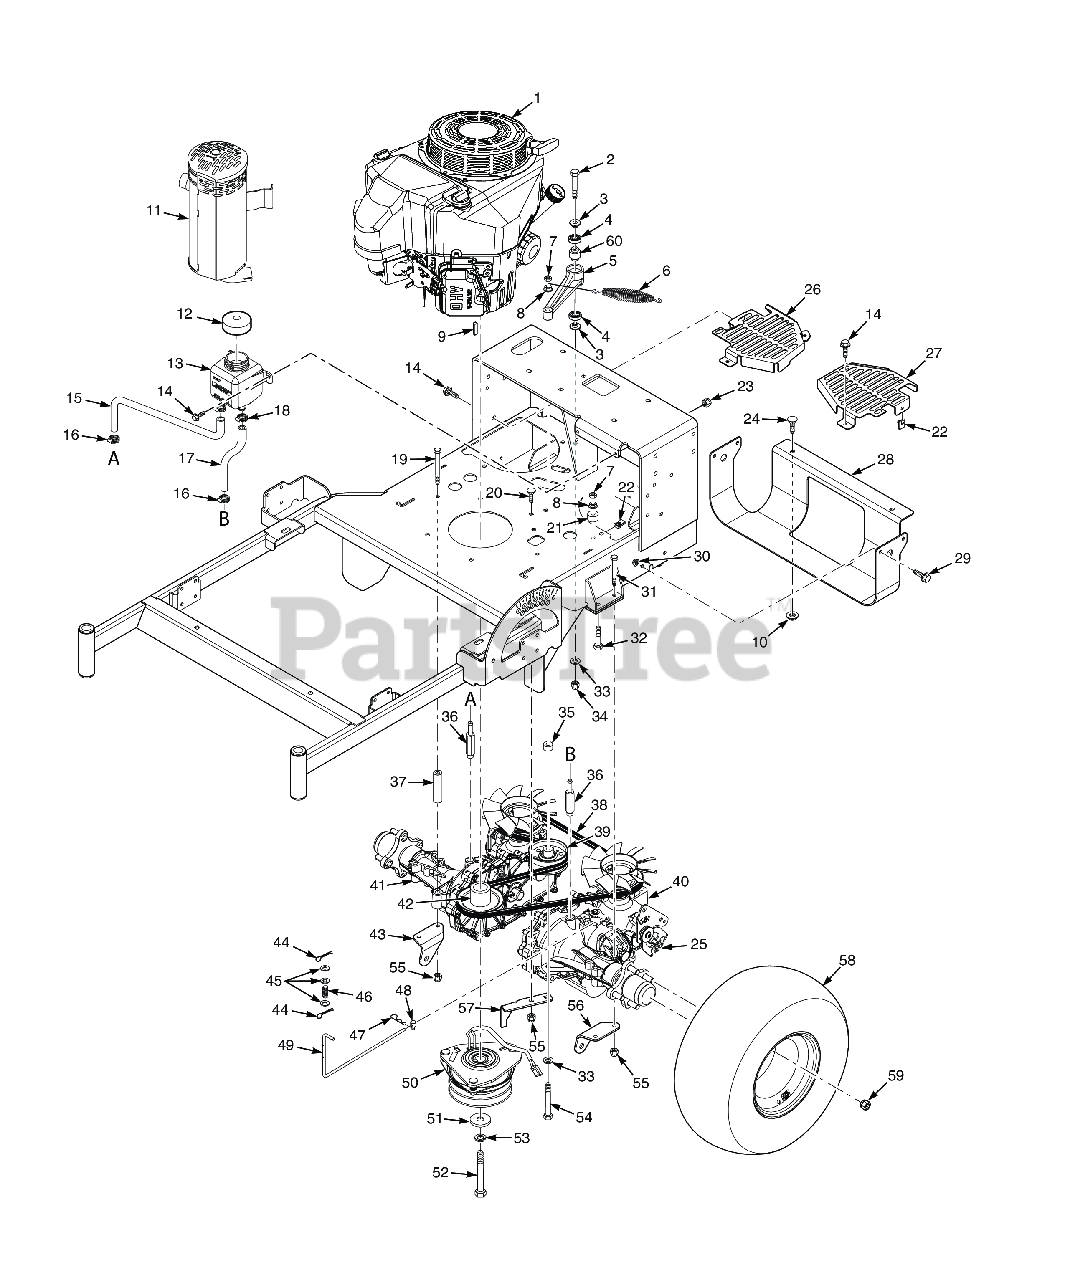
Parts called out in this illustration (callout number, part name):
1	Engine, Kawasaki 14FS (FS481V)
1	Engine, Kawasaki 15FS (FS541V)
1	Engine, Kawasaki FS600V (Recoil Start)
1	Engine, Kawasaki FS600V (Electric Start)
1	Engine, Kawasaki FS651V (Electric Start)
2	Bolt, Hex Head 3/8-16 x 3" - 52"
3	Spacer, Controls
4	BEARINGS, BALL, NEUTRAL RETURN
5	Trans. Idler Arm Assy. (Includes 24, 79)
6	Spring, Transmission Idler
7	Bolt, Hex Head 3/8-16 x 1" Ser. Flg.
8	NUT, 3/8-16 SERRATED FLANGE HEX HEAD
9	KEY, 1/4 X 1/4 X 2-1/2"
10	Nut, Push-On 5/16-18
11	Muffler, Kawasaki (FS481, FS541, FS600)
12	Cap, Hydraulic Tank
13	Reservoir Assembly
14	Bolt, Serrated Flange Hex Head 1/4 x 20 x 3/4"
15	Hose, RH Transmission
16	Clamp, .69" Max. / .25" Min. Dia.
17	Hose, LH Transmission
18	Clamp, Cable 3/4" I.D.
19	Bolt, Hex Head 5/16-18 x 6-1/2"
20	Bolt, Carriage 5/16-18x1" (large frame units only)
21	SPACER, J PULL ROD
22	Bolt, Hex Head 3/8-16 x 1"
23	HEX, NUT, ELASTIC STOP LOCK, 1/4-20
24	Bolt, 5/16-18 x .75 RHSN Carriage
25	Spring, RTN
26	Fan Cover, RH
27	Fan Cover, LH
28	Skid Plate
29	Capscrew, 5/16-18 x .75 Serrated Flange Hex Head
30	Nut, Serrated Flange 5/16-18 (Right Front Engine Mounting, Briggs and Kohler Only)
31	Bolt, Hex Head 5/16-18 x 3.00"
32	Bolt, Hex Head 3/8-16 x 2-1/2" 1.5 Thread Grd.8
33	Flatwasher, 3/8 (.391 x .938 x .105 HD) Grade 8
34	HEX NUT, ELASTIC STOP LOCK, 3/8-16
35	Spacer, Idler Pulley - SFZ61
36	Fitting, Transmission - SFZ61
37	Spacer, Axle
38	Belt, Transmission Drive
39	Pulley, 3-1/2" Dia.
40	Transaxle Assy., (ZH-GMCC-3LUB-1MXX)
41	Transaxle Assy., (ZH-KMCC-3LUC-1MXX)
42	Pulley, 4-1/2" Dia. - 1" Bore
43	Pusharm Mount Bracket, RH
44	COTTER PIN, 3/32 X 1"
45	Flatwasher, 1/4" (.312 x .750 x .065")
46	Spring, Dump Valve Link
47	Pin, Rue Cotter 3/8" Diameter
48	Joint, Swivel
49	Link, Dump Valve
50	Electric Clutch Assembly
51	Flatwasher, 7/16-.469 x 1.75 x .25 (48, 52)
52	Bolt, Hex Head 7/16-20 x 3" w/t Patch
53	Lockwasher, 7/16� Spring
54	Capscrew, Hex Head 3/8-16 x 3-3/4"
55	HEX NUT, ELASTIC STOP LOCK, 5/16-18
56	Pusharm Mount Bracket, LH
57	Bracket, Anti-Rotation
58	Wheel Assembly (#12 tire mounted to #13 rim)
58	Tire 18 x 8.5-8 (48" Only)
59	Wheel Nut, 1/2-20 x 13/16
60	Spacer, Bearing
